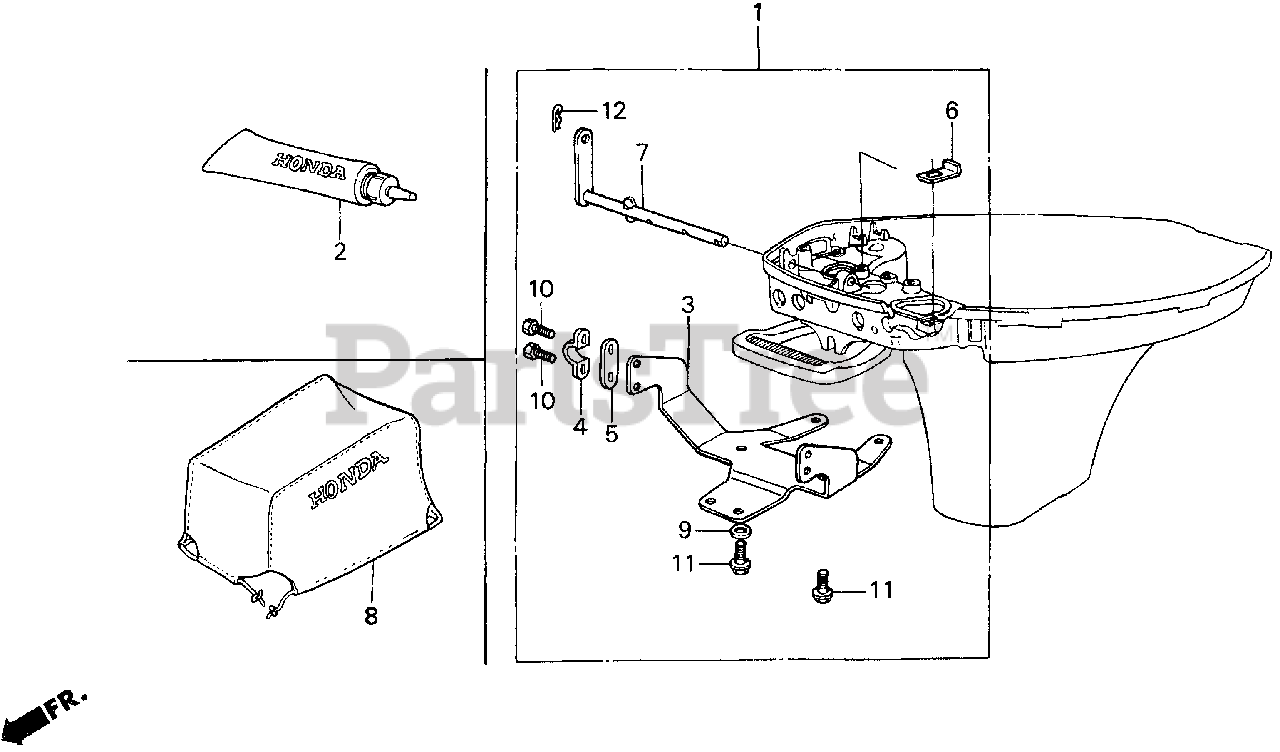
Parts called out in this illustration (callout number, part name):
1	CONTROL KIT, REMOTE
2	TUBE, GEAR OIL
3	BRACKET, STEERING
4	CLAMP, CABLE
5	SHIM, CABLE CLAMP
6	STOPPER, THROTTLE ARM
7	LEVER, SHIFT
8	COVER, BODY
9	WASHER, PLAIN (6MM)
10	BOLT, HEX. (5X10)
11	BOLT, HEX. (6X12)
12	PIN, LOCK (6MM)
